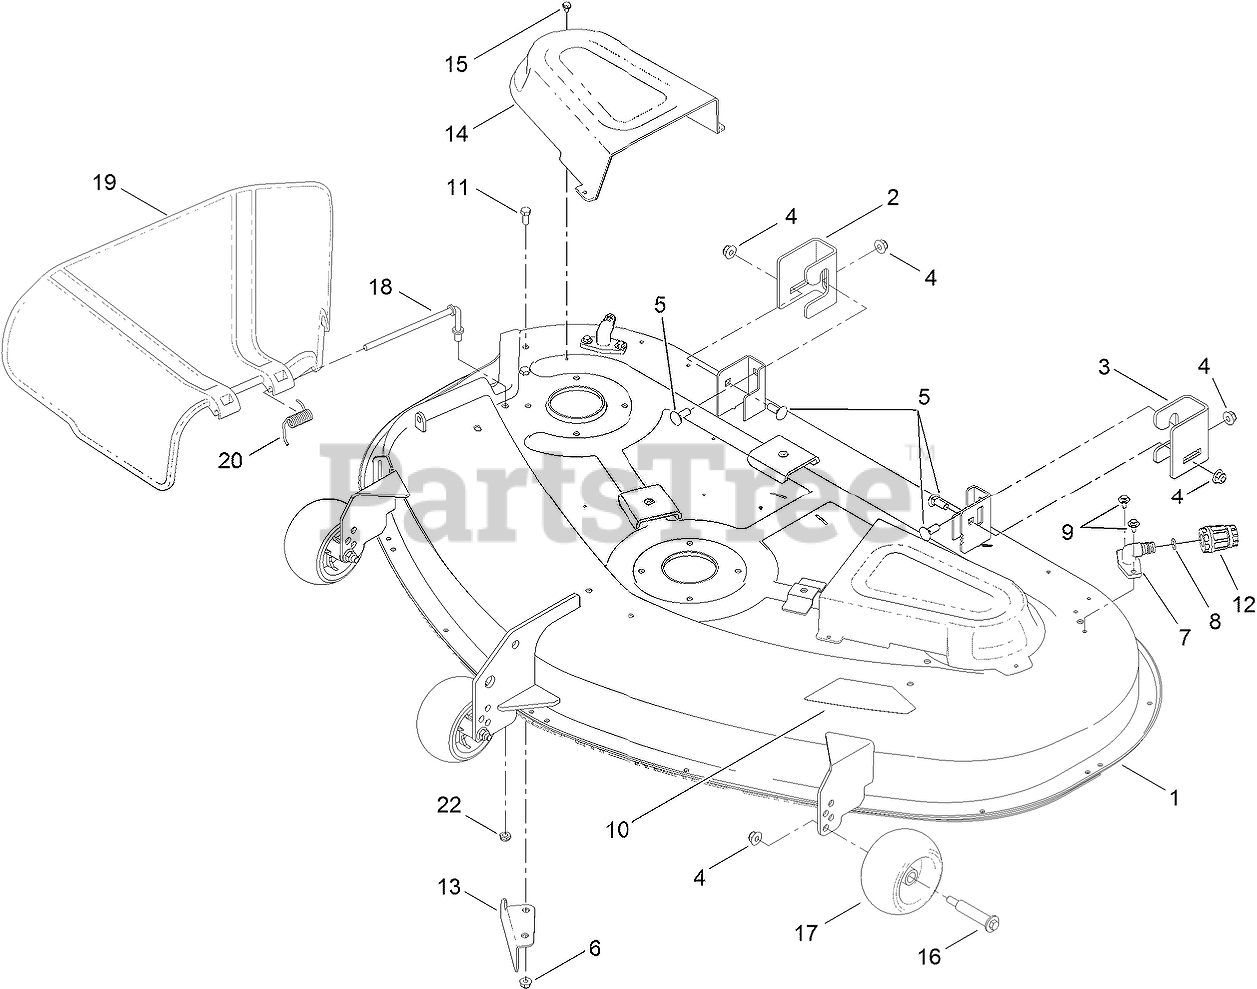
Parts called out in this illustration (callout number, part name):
1	50 INCH DECK AND DECAL ASM
2	BRACKET-HANGER, RH
3	BRACKET-HANGER, LH
4	NUT-HF, NI
5	BOLT-CARR
6	NUT-HF, NI
7	FITTING-WASHOUT
8	O-RING
9	SCREW-HHFTF
11	SCREW-HH
12	CONNECTOR-HOSE
13	BAFFLE-CUTOFF
14	COVER-BELT
15	SCREW-HWHTF
16	BOLT-SHOULDER
17	ROLLER-SCALP, ANTI
18	ROD-PIVOT
19	DEFLECTOR
20	SPRING-TORSION
22	NUT-LOCK, NI
